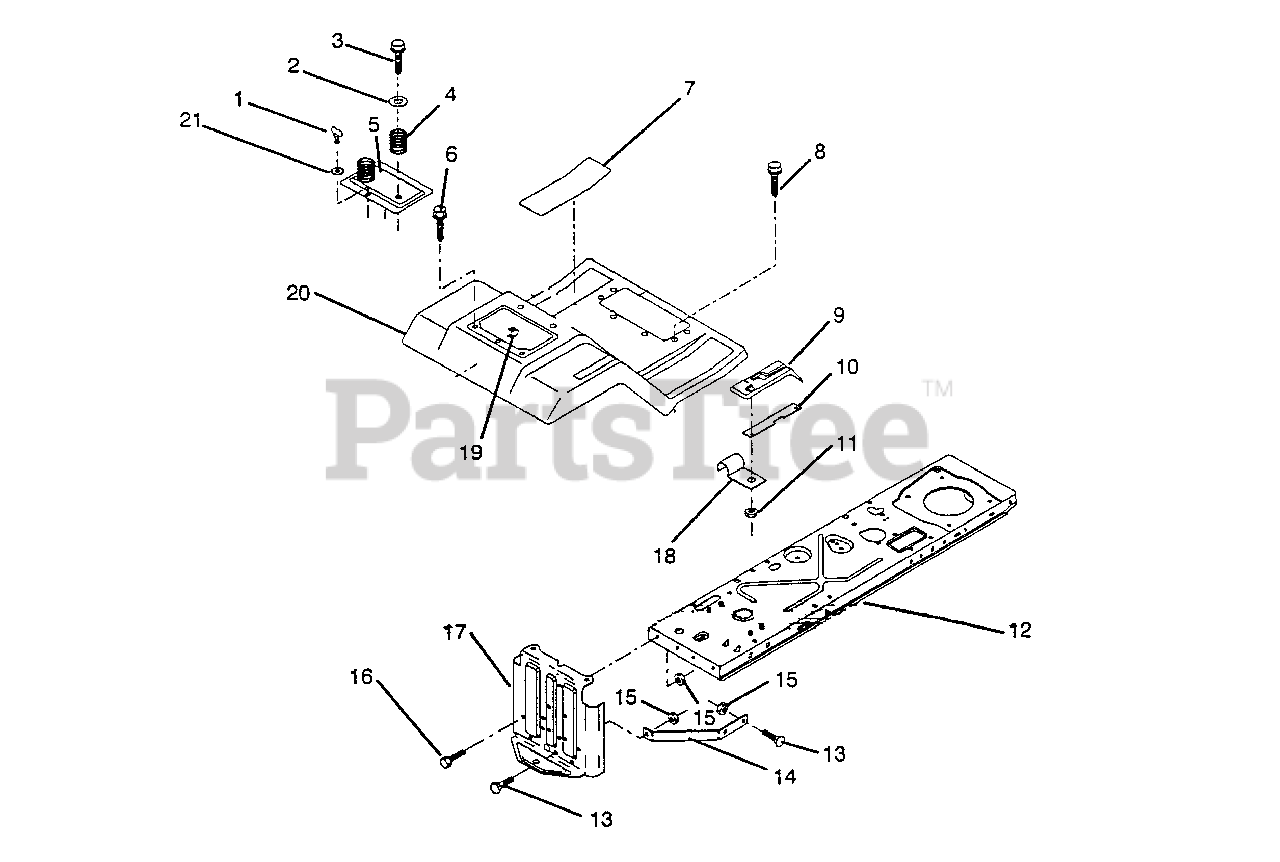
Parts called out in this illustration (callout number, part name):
1	Stud 1/4 Turn
2	Washer 13/32 x 1-1/4 x 12 Ga.
3	Screw, Hex Wsh. Thrdrol. 3/8-16 x 3/4
4	Spring, Compression, Seat
5	Door, Fender
6	Screw, Hex Wsh. Thrdrol. 5/16-18 x 1/2
7	Pad, Footrest
8	Screw, Hex Wsh. Thrdrol. 5/16-18 x 3/4
9	Console, Shift Control
10	Bar, Shift Lock
12	Assembly, Frame
13	Bolt, Carriage 5/16-18 UNC x 3/4
14	Brace, Drawbar
15	Nut, Crownlock 5/16-18
16	Bolt, Hex Hd. 5/16-18 UNC x 3/4
17	Drawbar
18	Clip, Insulated
19	Receptacle, 1/4 Turn
20	Fender/Footrest
21	Retainer, 1/4 Turn
